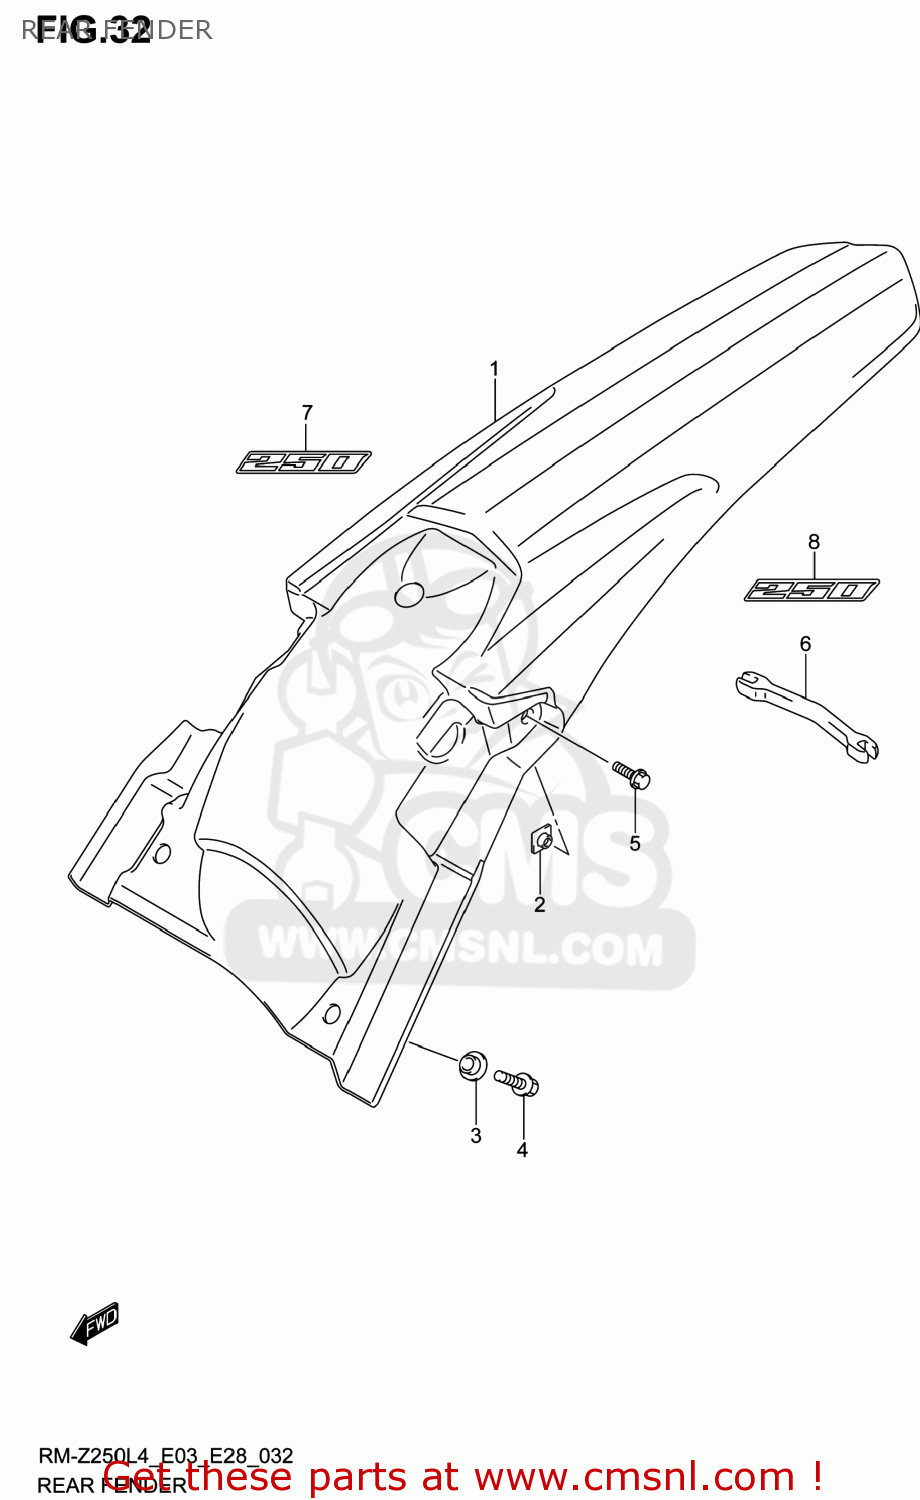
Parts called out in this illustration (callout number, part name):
1	FENDER,RR
2	NUT,RR REFLECTOR
3	WASHER,FR FENDER
4	BOLT
5	BOLT
6	OPEN SPANNER(6.4X6.8)
7	EMBLEM,RR FENDER,R
8	EMBLEM,RR FENDER,L
